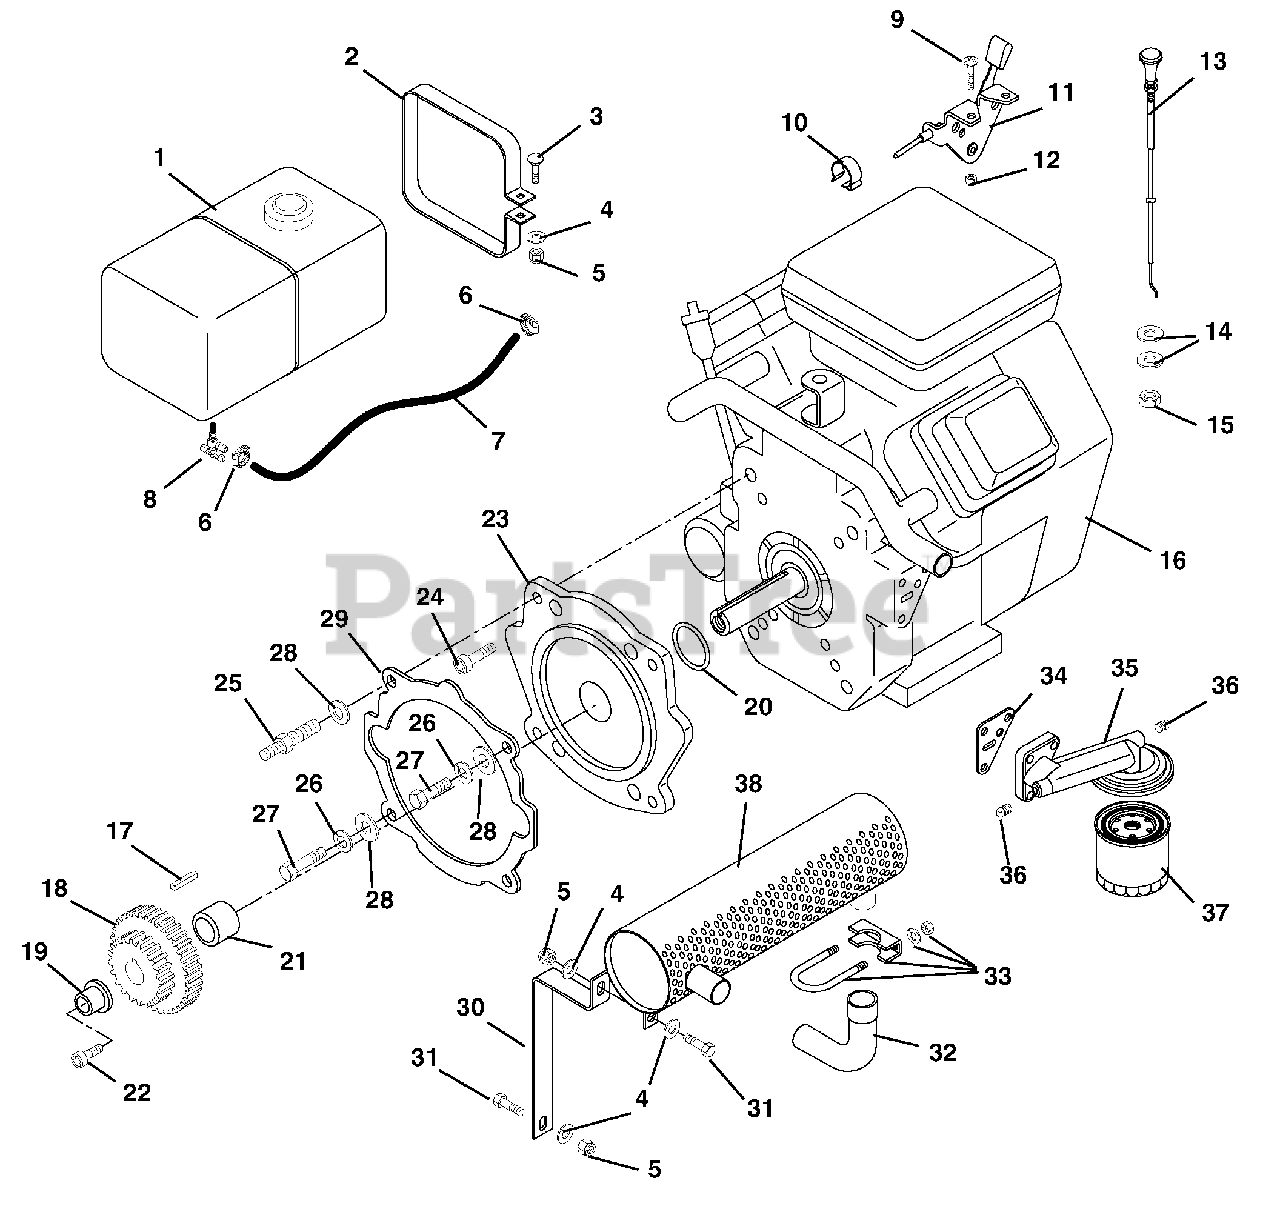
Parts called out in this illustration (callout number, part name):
1	Tank-Fuel, w/Cap-Black, 2-Wheel
2	Strap-Fuel Tank
3	Bolt-Round Head Square Neck .25-20 x 1.75
4	Washer-Flat-Steel .281 x .620 x .065
5	Nut-Locking-Center .250-20 Grade 2
6	Clamp-Hose
7	Gas Line-Bulk
8	Valve and Strainer
9	Screw-Machine 10-24 x .50
10	Clamp
11	Control-Choke Plated
12	Nut-Locking Nylon 10-24
13	Lever-Choke Control
14	Washer-Flat-Steel .406 x .812 x .065
15	Nut-Jam .375-24
16	Engine-16 HP B & S
17	Key-Square .248 x 1.0 x .248
18	Gear
19	Pilot-Gear
20	O-Ring 1.850 x 2.270 x .210
21	Spacer 1.05 x 1.31 x 1.54
22	Screw-Machine .38-24 x 1.00
23	Adapter
24	Screw-Socket Head .44-14 x 1.00
25	Stud
26	Washer-Lock .438 x .133
27	Bolt-Hex .44-14 x 1.50
28	Washer-Flat-Steel .459 x .938 x .065
29	Gasket-Chassis to Adapter
30	Bracket-Exhaust
31	Bolt-Hex .25-20 x 1.00 Grade 5
32	Elbow
33	Clamp-Muffler 1.25
34	Gasket-Oil Filter Adapter
35	Oil Filter Manifold
36	Plug-Pipe 1/16-27
37	Filter-Oil
38	Muffler-16 HP
